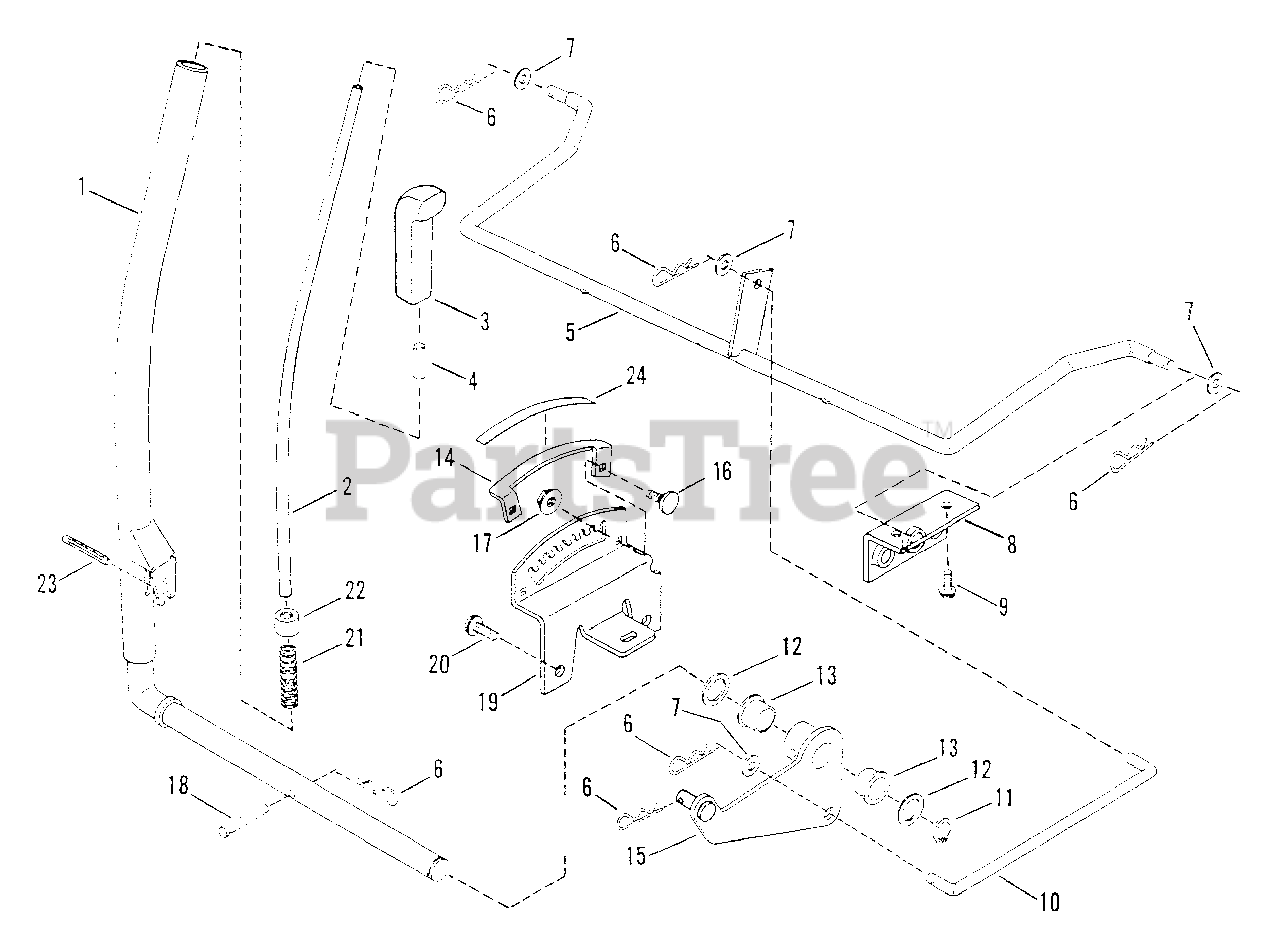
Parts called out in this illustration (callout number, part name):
1	ARM, Implement Lift Lever
2	ROD, Lift Lever
3	GRIP, Lift Lever
4	CAP, Lift Release
5	ARM, Rear Lift
6	PIN, 3/32 x 1 1/2" Hair
7	WASHER, 3/8" Flat
8	BRACKET, Hanger
9	SCREW, 5/16-18 x 5/8" Self Tap.
10	LIFT-ROD
11	RING, Retaining
12	WASHER, Lift Lever
13	BEARING, Lift Lever
14	INDICATOR, Cut Height
15	PIVOT ASSEMBLY, Lift Lever
16	BOLT, 1/4-20 x 5/8" Flat Head Carr.
17	NUT, 1/4-20 Hex Flange Lock
18	PIN, 5/16 x 1 11/16" Clevis
19	QUADRANT, Lift Lever
20	SCREW, 5/16-18 x 5/8" Self-Tap
21	SPRING, Lift Lever
22	PLUG, Lift Lever
23	PIN, 3/16 x 2" Groove
24	DECAL, Cut Height
